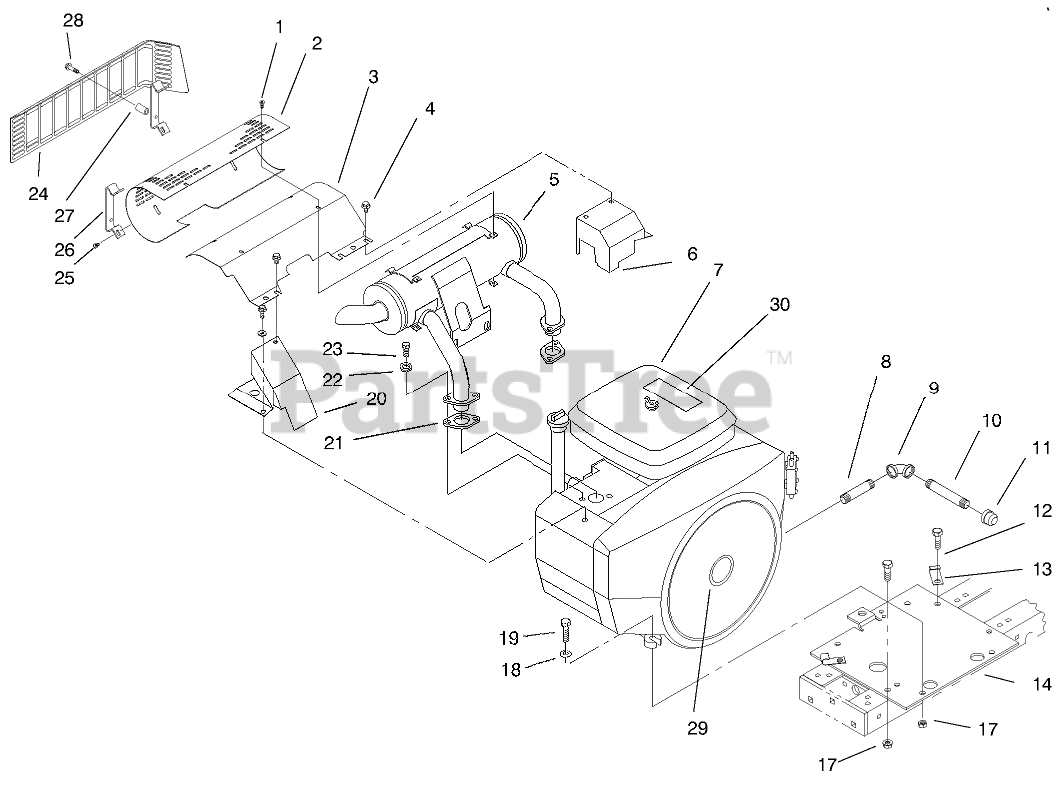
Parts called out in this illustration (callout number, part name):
1	SCW 10-24 STAINLESS
2	SHIELD - HEAT
3	Baffle-Deflector
4	SCREW-HWHTF
5	MUFFLER-EXHAUST
6	COVR-EXHAST (BLACK)
7	Engine-Onan
7	ENGINE - ONAN,16 HP
8	Pipe
9	ELBOW 3/8 90 DEG
10	PIPE-NIPPLE 3/8 X 4"
11	CAP-PIPE
12	SCREW-HH
13	CLIP
14	Plate-Engine
17	NUT-LOCK, NI
18	WASHER-FLAT
19	SCREW-HH
20	COVR-EXHAST (BLACK)
21	GASKET
22	WASHER-LOCK
23	SCREW-HH
29	NAME-PLATE TORO LOGO
30	DECAL-PWR PLUS 16 PL
31	WASHER-LOCK
